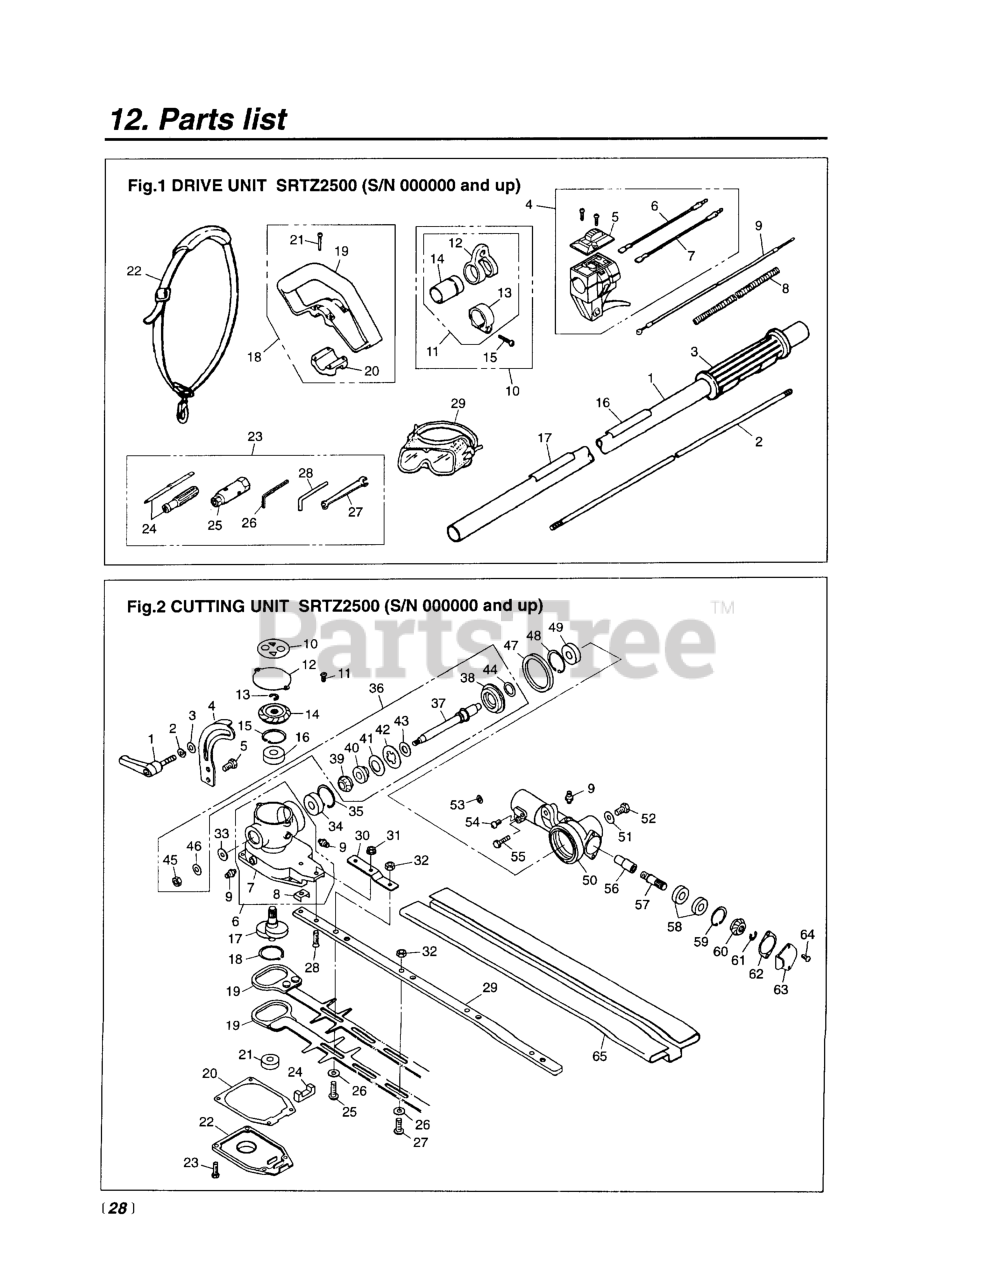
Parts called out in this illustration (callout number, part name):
1-1	PIPE COMPLETE
1-2	SHAFT
1-3	GRIP (RPLS 3577-32140 & 3220-
1-4	LEVER COMP (RPLS. T3065-12200)
1-5	COVER (USE 848-8RA-0340)
1-6	CORD (A), BLACK
1-7	CORD (B), RED
1-8	TUBE (RPLS 4900-72141)
1-9	CABLE (RPLS 5580-83100)
1-10	HANGER ASSEMBLY
1-11	HANGER COMPLETE
1-12	HANGER
1-13	CLAMP
1-14	SLEEVE
1-15	SCREW, M5 x 25
1-16	NAMEPLATE
1-17	LABEL (CAUTION)
1-18	HANDLE ASSEMBLY
1-19	HANDLE
1-21	SCREW, M5 x 35
1-22	STRAP ASSY.
1-24	SCREWDRIVER
1-25	SOCKET
1-26	WRENCH (TOOL)
1-27	SPANNER, 8 X 10 (RPLS 2540- )
1-28	BAR
1-29	GOGGLE
2-2	WASHER, M6 X 15
2-3	WASHER, 6X15X2.0
2-4	PLATE (RPLS-13140)
2-6	CASING (RPLS -13210)
2-7	CASING A
2-8	PLATE
2-9	FITTING, GREASE
2-10	LABEL
2-11	SCREW, M4 X 8
2-13	RING, SNAP
2-14	GEAR, BEVEL
2-15	RING, SNAP, M26 X 1.2
2-16	BEARING
2-17	CRANKSHAFT
2-18	RING, SNAP, M28 X 1.5
2-19	BLADE, SRT, 24
2-20	GASKET
2-21	BEARING
2-22	COVER
2-23	BOLT (RPLS 6782-13450)
2-24	FELT
2-26	WASHER (RPLS 3873-11760)
2-27	SCREW
2-28	SCREW, M5 X 20
2-29	PLATE, GUIDE
2-30	PLATE (RPLS 6780- )
2-31	NUT, M5
2-32	NUT, M6
2-33	WASHER, 6X15X2.0
2-34	BEARING
2-35	RING, SNAP, M22 x 1.2
2-37	SHAFT
2-38	GEAR (B)
2-39	GEAR (C)
2-40	BOSS
2-41	WASHER, SPRING
2-42	PLATE
2-43	WASHER
2-44	WASHER
2-45	NUT, M6 X 5
2-46	WASHER, M6 X 15
2-47	O-RING
2-48	RING, SNAP, M26 X 1.2
2-49	BEARING
2-50	CASE- B
2-51	WASHER, 6X15X2.0
2-53	WASHER
2-54	BOLT, M5 X 10
2-55	BOLT
2-56	JOINT (REPLACES T3078-13810)
2-57	SHAFT, GEAR
2-58	BEARING
2-59	RING, SNAP, M22 x 1.2
2-60	GEAR, BEVEL
2-61	RING, SNAP
2-62	PACKING
2-64	SCREW, M4 X 10
2-65	COVER, BLADE
